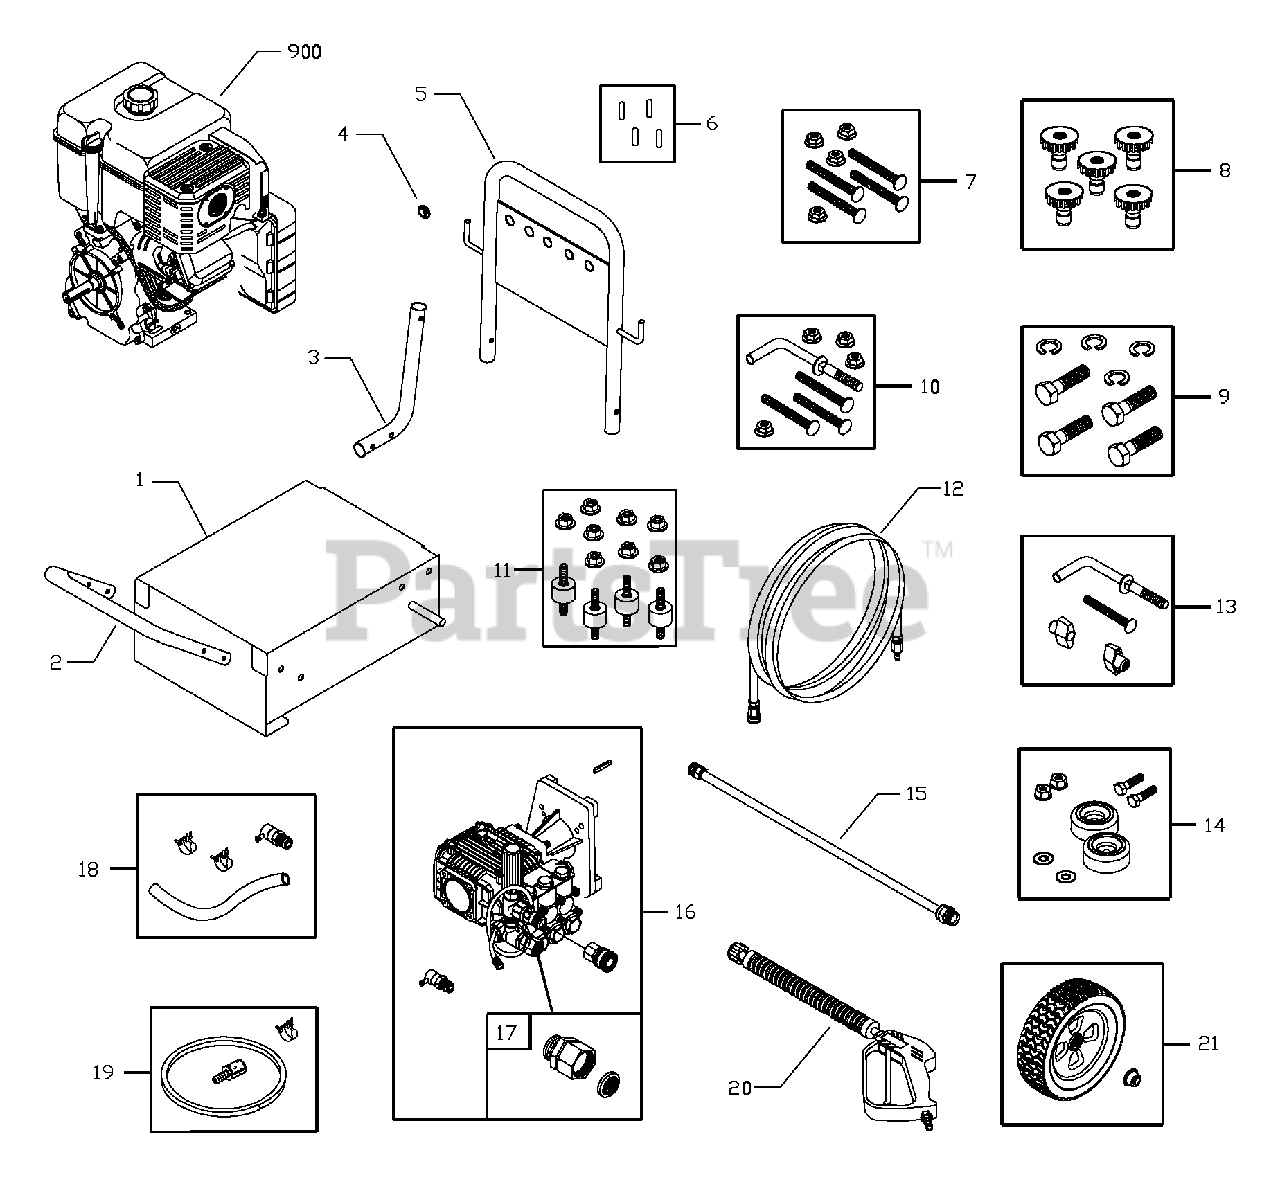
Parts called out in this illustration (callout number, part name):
7	KIT, Lower Handle Hardware
9	KIT, Pump Mounting Hardware
10	KIT, Bumper Mounting Hrdwr
11	KIT, Engine Mounting Hrdwre
12	HOSE
13	KIT, Upper Handle Hardware
14	KIT, Vibration Mount
15	EXTENSION, QC
17	KIT, Garden Hose Inlet
18	KIT, Thermal Relief
19	KIT, Chemical Hose
20	GUN
900	ENGINE
